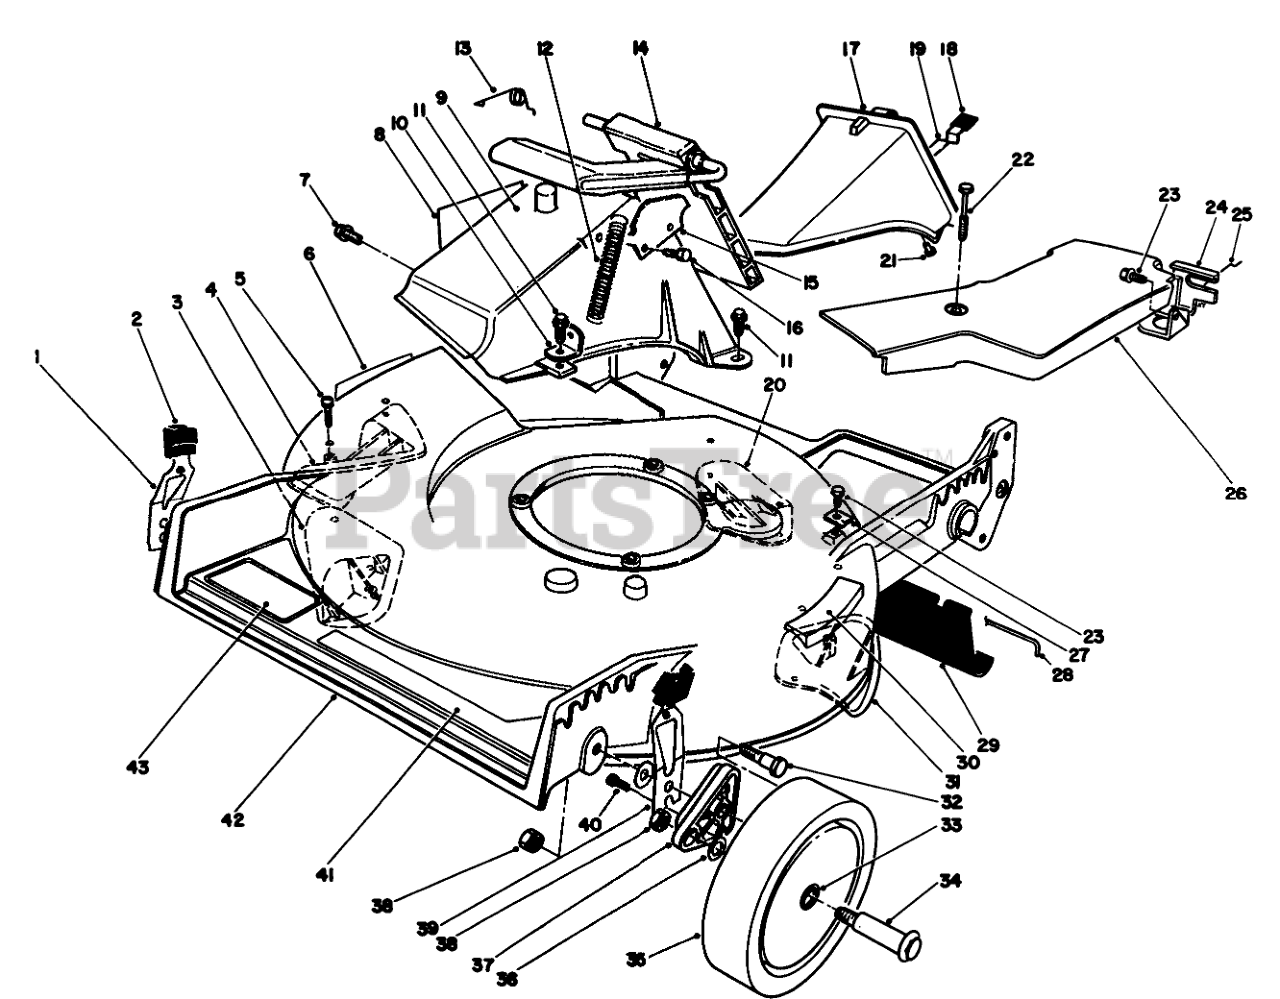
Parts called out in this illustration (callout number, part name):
1	RH SPRING ARM ASSEMBLY
2	KNOB-ARM
3	KICKER
4	KICKER
5	SCREW-PPH
6	DECAL-DANGER
7	SCREW AND WASHER ASM
8	DECAL - DANGER
9	TUNNEL-DISCHARGE
10	Bracket-Spring
11	SCREW-HWH
12	SPRING-DOOR
13	RETAINER-DOOR
14	DOOR ASSEMBLY
15	DOOR LATCH PLATE
16	SCREW-PLASTITE
17	Discharge Plug Assernbly (Incl. Ref. #18-19 & 21)
18	GRIP-LATCH
19	LATCH-PLUG, DISCHARGE
20	KICKER
21	RIVET-HEAD, FLAT
22	SCREW-HHFTF
23	SCREW-HWHTF
24	Bracket-Adj. Trac
25	RETAINER-CABLE
26	BELT COVER
27	CLAMP-CABLE
28	ROD-SHIELD
29	SHIELD-TRAILING
30	DECAL - STEP PAD INT'L
31	KICKER
32	SCREW-SHOULDER
33	BUSHING
34	WHEEL BOLT
35	Wheel & Tire Assembly (Incl. Ref. #33)
36	WASHER
37	ARM-PIVOT, FRONT
38	Nut
39	LH SPRING ARM ASSEMBLY
40	SCREW-HWH
41	DECAL - DECK
42	Housing Assembly (Incl. Ref. #3-6, 20, 31, 5 on pg. 3, & 30-31 on pg. 4)
43	DECAL
